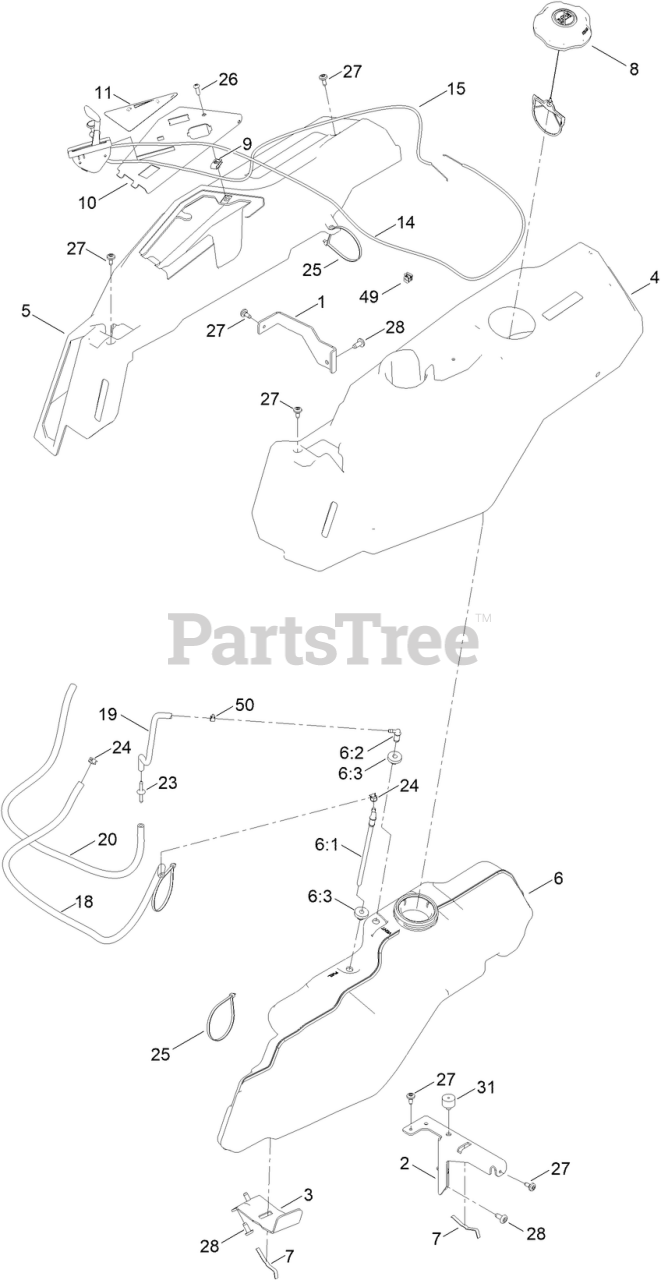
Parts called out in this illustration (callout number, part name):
1	BRACKET-POD
2	SUPPORT-POD, LH
3	SUPPORT-TANK, FUEL
4	POD-LH
5	POD-RH, MYRIDE
6	TANK-FUEL ASM
6:1	CONNECTOR-ELBOW, 90 DEG
6:2	FITTING-ELBOW 90
6:3	BUSHING
7	SPRING
8	CAP-FUEL, RATCHETING
10	PANEL - CONTROL
11	DECAL-PANEL, CONTROL
14	CABLE-THROTTLE
15	CABLE-CHOKE
18	HOSE-FUEL
19	HOSE-FUEL
20	HOSE, FUEL
23	ADAPTER ORIFICE
24	CLAMP-HOSE
25	TIE-CABLE
26	SCREW-PRH
27	SCREW-SHOULDER
31	BUMPER-GROMMET
49	CLIP-HARNESS
50	CLAMP-HOSE
